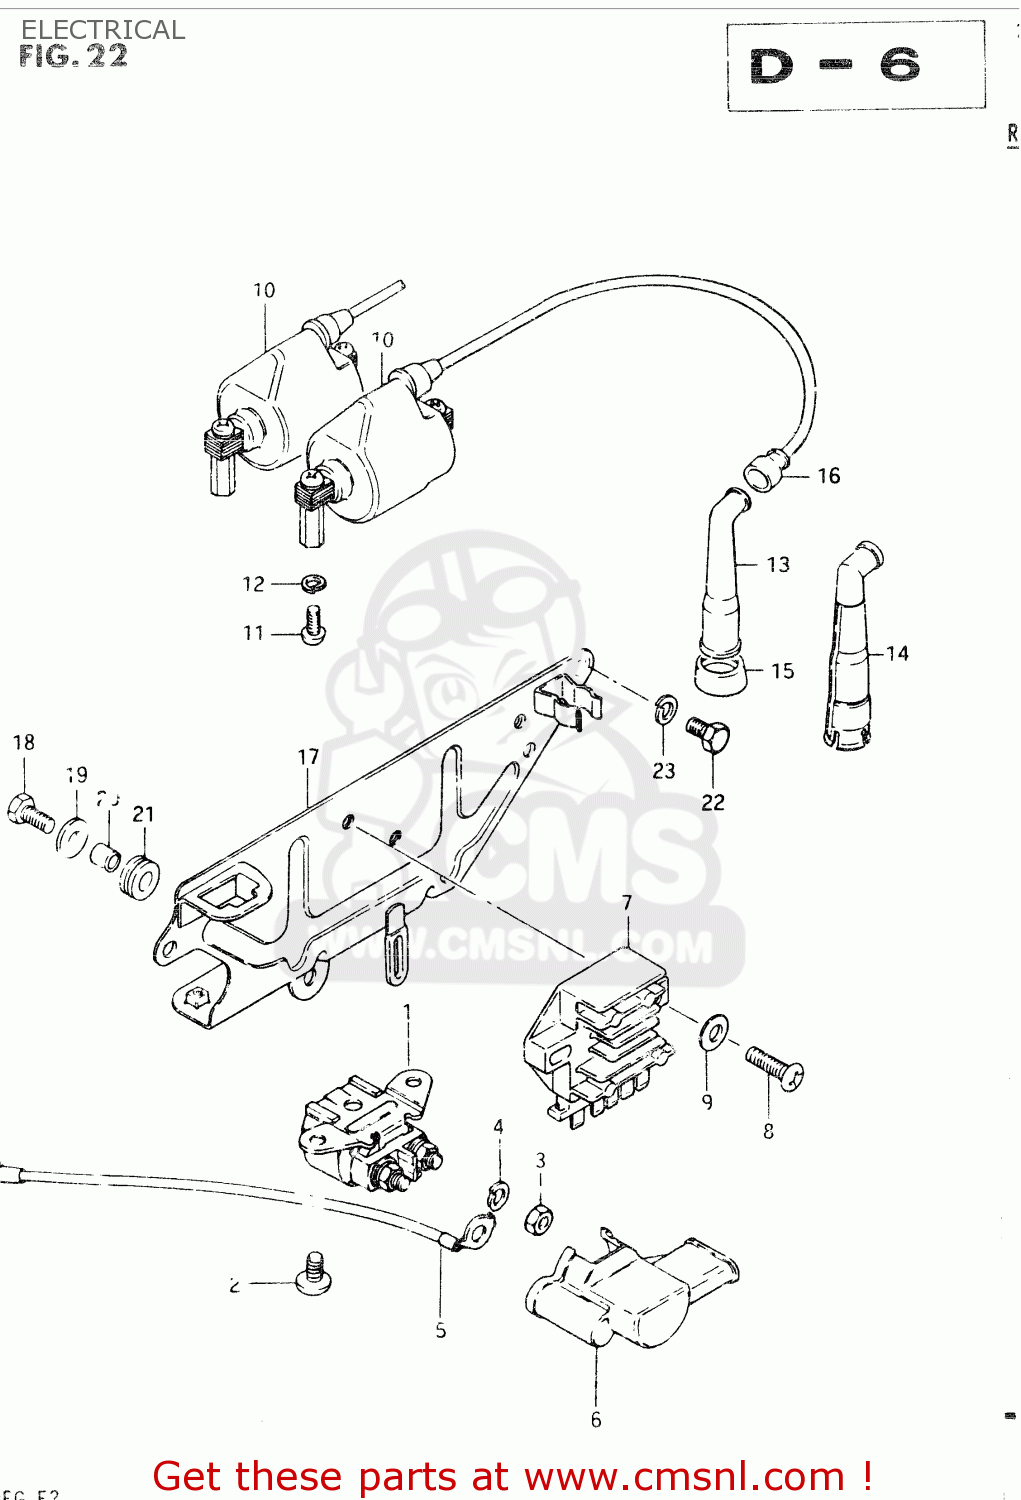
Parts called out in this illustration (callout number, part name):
1	RELAY ASSY,STARTING MOTOR
2	SCREW
3	NUT
4	WASHER,LOCK
5	WIRE,STARTER MOTOR LEAD
6	CAP,STARTER RELAY
7	RECTIFIER ASSEMBLY
8	SCREW
9	WASHER
10	COIL ASSEMBLY,IGNITION
11	SCREW
12	LOCK WASHER
13	CAP ASSY,SPARK PLUG
14	CAP, SPARK PLUG
15	SEAL,SPARK PLUG CAP
16	SEAL,SPARK PLU
17	HOLDER COMP,ELECTRONIC PARTS
18	BOLT,M6X1X20
19	WASHER
20	SPACER (6.1X8X9.5)
21	CUSHION
22	BOLT
23	WASHER,LOCK
